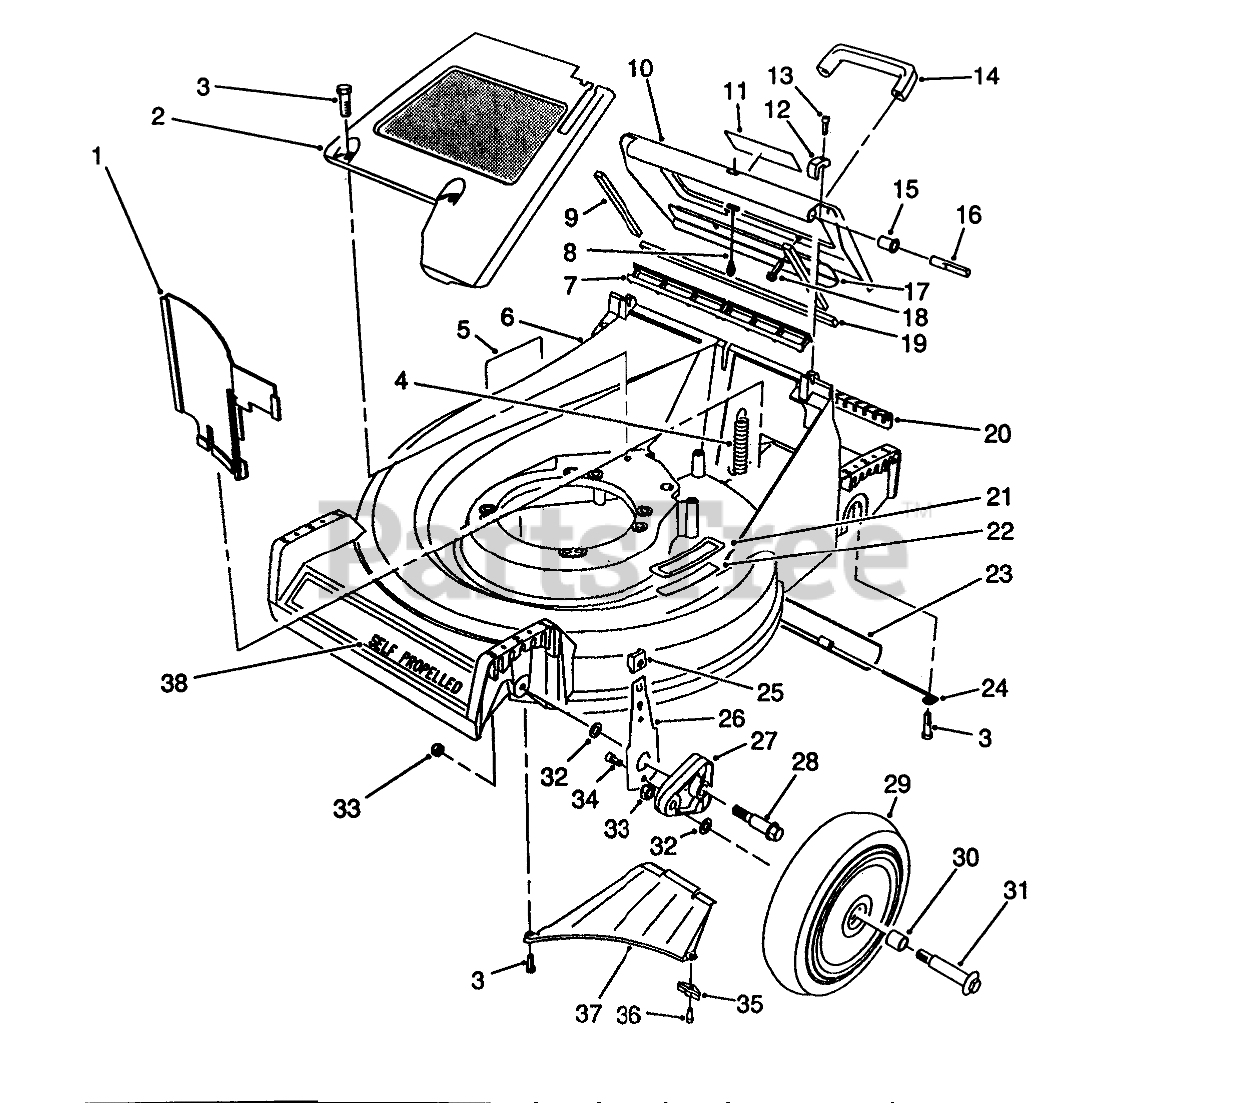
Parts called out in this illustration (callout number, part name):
1	PANEL-VERTICAL
2	PaneI-Screen
3	SCREW-HWHTF
4	EXTENSION-SPRING
5	DECAL-DANGER
6	Housing-21" (Incl. Ref. #5, 21 & 22)
7	DOOR SEAL
8	DOOR CABLE
9	DOOR SIDE SEAL
10	Door-Discharge (Incl. Ref. #9, 11, 17 & 19)
11	DECAL - WARNING
12	HINGE CLAMP
13	SCREW-HSH
14	HANDLE-DOOR
15	DOOR BUSHING
16	HINGE PIN
17	DOOR - BRACE
18	SCREW-HWH
19	DOOR END SEAL
20	ACCESS COVER
21	STEP PAD
22	STEP PAD DECAL
23	TRAILING SHIELD
24	LH SHIELD HANGER
25	KNOB-ARM
26	FRONT SPRING ARM ASM
27	ARM-PIVOT, FRONT
28	BOLT-SHOULDER
29	Wheel & Tire Assembly (Incl. Ref. #30)
30	BUSHING
31	WHEEL BOLT
32	WASHER
33	Nut
34	SCREW-HSH, THREAD FORMING
35	Bracket-Discharge
36	SCREW-HWHTF
37	Ramp Discharge
38	DECAL - DECK
